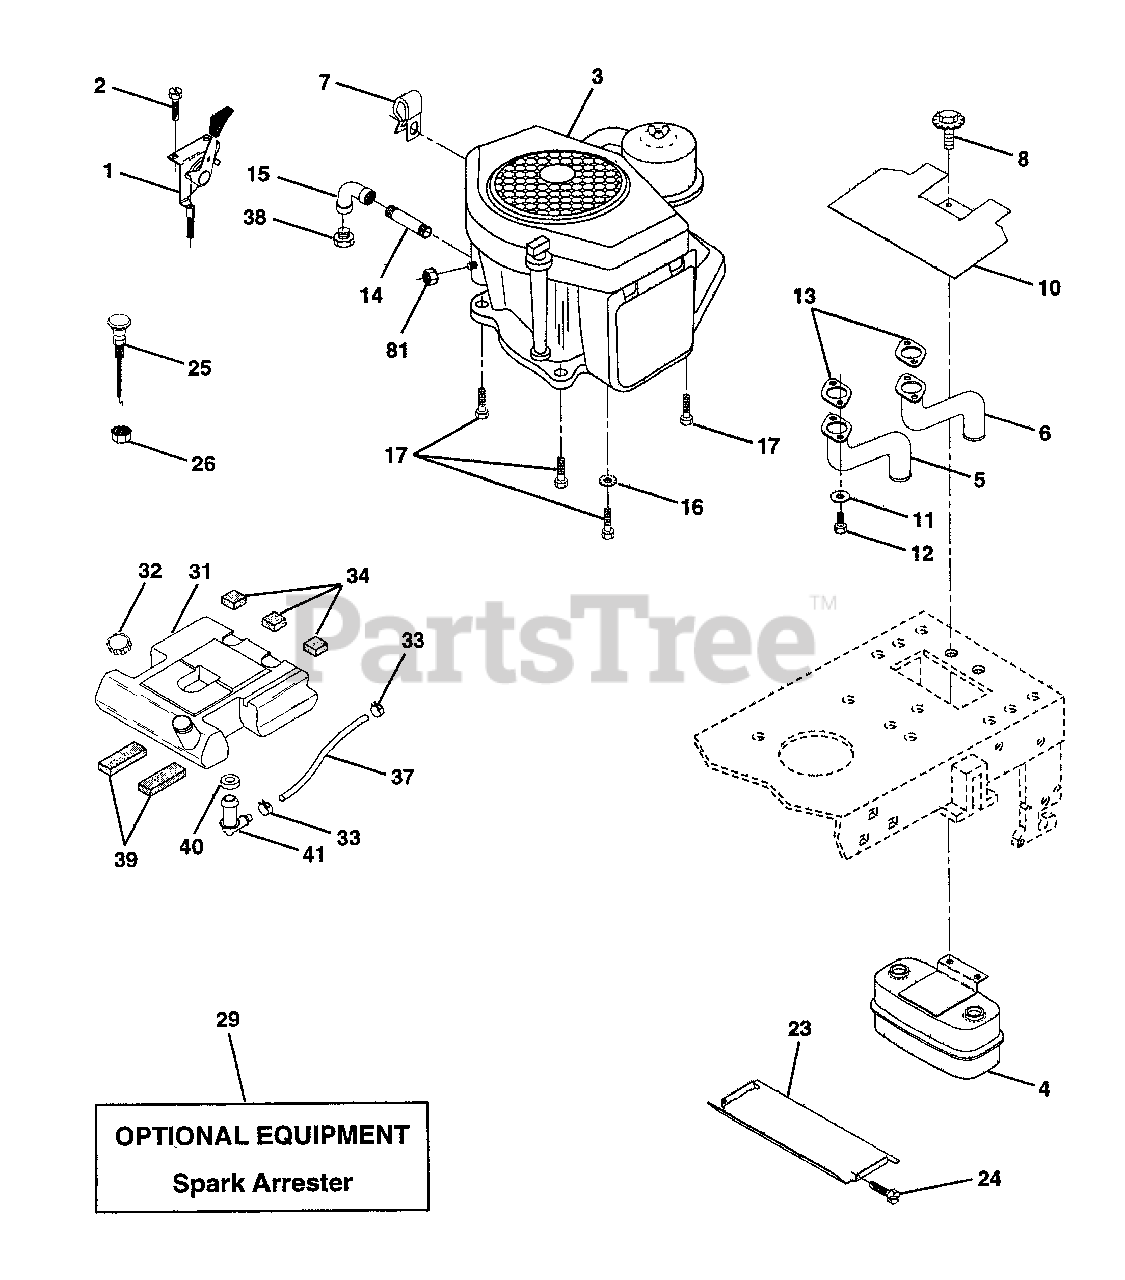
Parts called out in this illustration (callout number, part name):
1	Control Throt LH Blk 180 46"
2	Screw Hex Thd Cut 1/4-20x5/8 T
4	Muffler Asm Twin Lo-Tone
5	Pipe Exhaust CV18/20 LH
6	Pipe Exhaust CV18/20 RH
7	Clip, Fuel Line
8	Bolt 5/16-18unc x 3/4 W/Sems
10	Shield Heat Muffler CV18/20
13	Muffler Gasket
14	Nipple Pipe 3/8 Npt X 4-1/2"
15	Elbow Std 90 Degree 3/8-18 Npt
16	Washer Lock Ext Tooth 3/8
17	Screw Thdrol 3/8-16 x 1-1/2
23	Shield Heat Browning LT/YT
24	Screw Tap Hex #10-24unc X 1/2
25	Choke Control 37"
26	Nut, Keps 3/8-24 Unf
29	Kit Spark Arrestor
31	Tank Fuel 3 50 Rear
32	Cap Asm Fuel Top N/Lany Vented
33	Clamp Hose Blk
34	Pad, Spacer
37	Line Fuel 7.5
38	Plug Oil Drain
39	Pad, Idler
40	Bushing
41	Stem Tank Fuel
81	Nut Flange 1/4-20 Starter Nut
